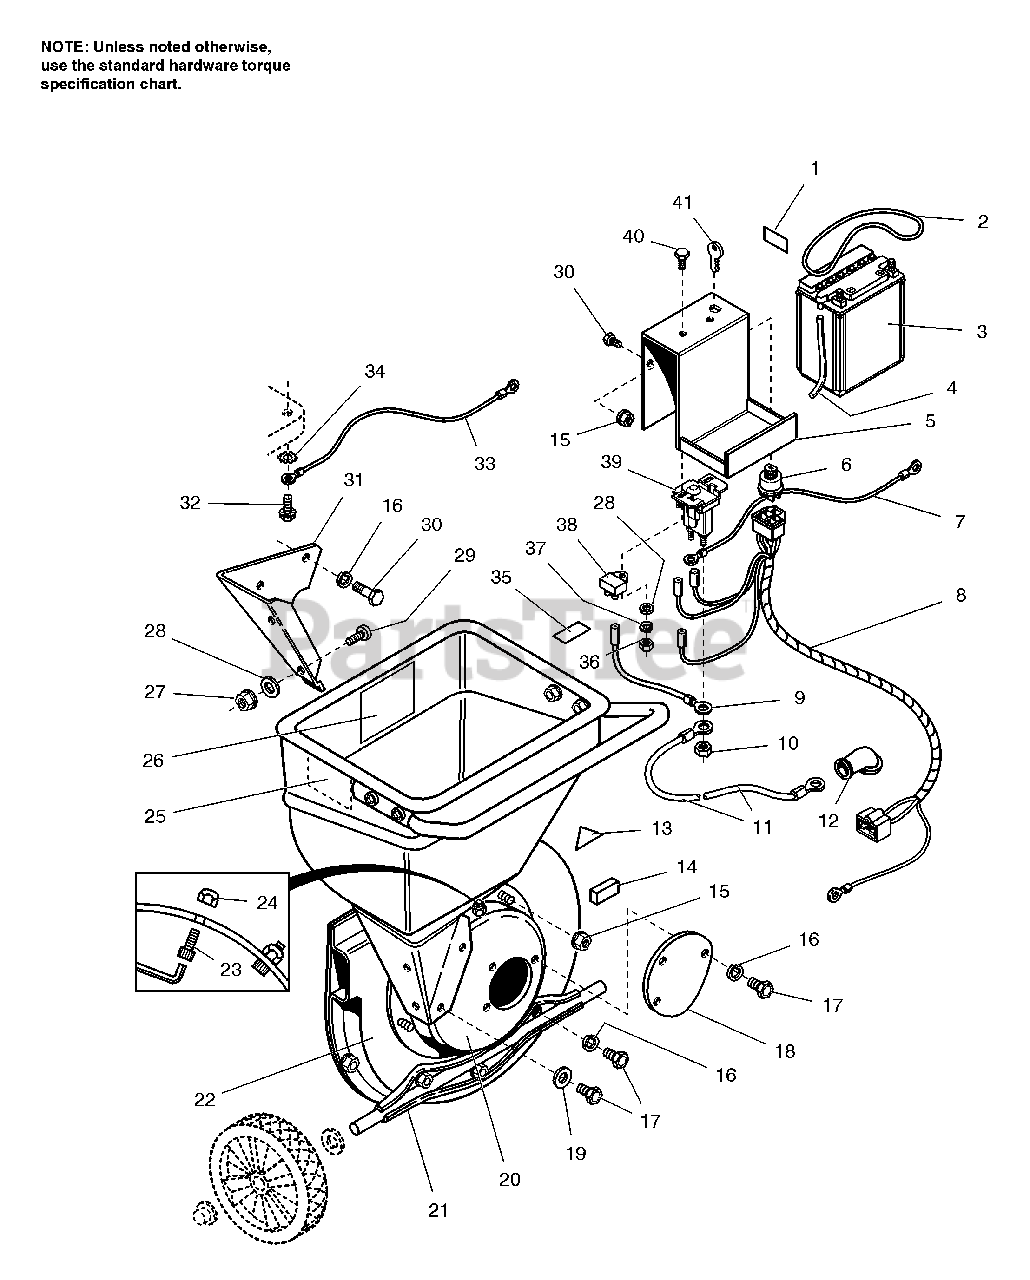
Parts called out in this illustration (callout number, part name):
1	DECAL, Ignition Switch
2	STRAP, Battery
4	TUBE, Battery
5	BOX, Battery
7	CABLE, #6 x 15, 5/16 + 1/4
9	WIRE ASSY, Circuit Breaker
10	NUT, Hex, 5/16-24
11	CABLE, #6 x 25, 5/16 + 1/4
12	COVER, Terminal
13	DECAL, OPEI
15	NUT, Hex whiz lock, 5/16-18
16	LOCKWASHER, Spring, 5/16
17	CAPSCREW, Hex. Hd., 5/16-18 x 1/2, Grade 5
18	COVER, Rotor Housing
19	WASHER, Plain, 11/32 x 7/8 x 1/16
20	HOUSING ASSY., Rotor
22	FAN HOUSING ASSY.
23	CAPSCREW, Socket Hd., 5/16-18 x 1/2
24	NUT, Fiber lock, 5/16-18
25	DECAL, Danger
26	DECAL, Caution/Operate
27	NUT, Flange, 2-way Lock, 1/4-20
28	WASHER, Plain, 17/64 x 5/8 x 3/64
29	SCREW, Button Hd. Hex Socket, 1/4-20 x 3/4
30	CAPSCREW, Hex Hd., 5/16-18 x 3/4
31	LINER, Hopper
32	SCREW, taptite, 3/8-16 X 1-1/4
33	CABLE, #6 x 31, 3/8 + 1/4
34	LOCKWASHER, Ext., Tooth
35	DECAL, Patent
36	NUT, Hex, 1/4-20
37	LOCKWASHER, 1/4
38	CIRCUIT BREAKER
39	SOLENOID
40	CAPSCREW, Hex Hd. 1/4-20 x 5/8
41	KEY, Ignition
